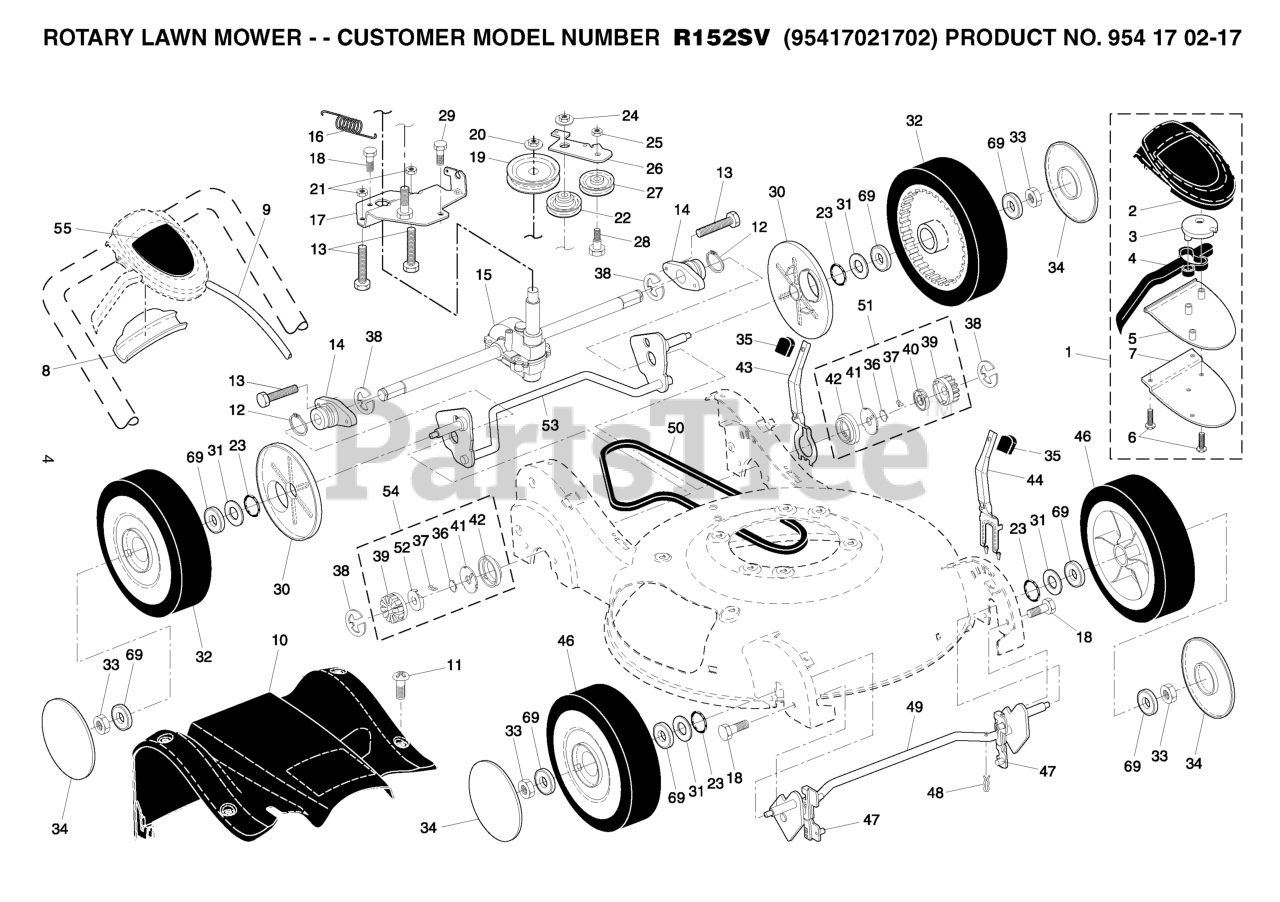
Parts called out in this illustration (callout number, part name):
1	CONTROL.DR.HV.RWGD.GRY/BLU
2	CASE.TOP.GRAY
3	PULLEY.CAM.DRIVE.CONTROL.HV
4	LEVER, DRIVE CONTROL
5	CASE BOTTOM
6	SCREW, PHILLIPS HEAD 10 X 5/8
7	BRACKET, DRIVE CONTROL
8	EZ WALK SNAP COVER PLATE
9	ASM.CABLE.
10	COVER ASM. DRIVE
11	SCREW
12	RETAINING RING (2 2)(3 2)
13	RP SCREW
14	BEARING.SUPPORT.ASSEM
15	TRANSMISSION.21.HI-VAC.EZ
16	SPRING.RETURN
17	BRACKET TRANSMISSION
19	RP PULLEY DRIVE
20	FLANGED LOCKNUT 3/8-16 ZINC
21	NUT
22	PULLEY.IDLER.V-BELT
23	O-RING
24	JAM NUT TI
25	NUT.CENTERLOCK.5/16-
26	ARM.IDLER.BZP
27	IDLER PULLEY
28	SHOULDER BOLT
29	SCREW 14-20 X 5/8
30	DUST COVER, WHEEL
31	WASHER.FLAT.1/2
32	WHEEL.9X2.25.PR.JUNG.BLK
33	HEX FLANGE LOCKNT
34	RB HUBCAP.3-SPOKE.SILVER
35	KNOB.SELECTOR.SPRG.H-GRY (2 2)
36	SPRING, TORSION
37	PAWL.DRIVE.21.EZ-WALK
38	E-RING 7/16 RE
39	GEAR, PINION
40	RETAINER.DRIVE.21.EZ-WALK.LT
41	DISC.DRIVE.21.EZ-WALK
42	SEAL.PINION
43	LEVER, SELECTOR, HEIGHT, REAR
44	LEVER, SELECTOR, HEIGHT, FRONT
46	WHEEL.9X2.25.LP.JUNG.BLACK
47	BUSHING.FRONT.TORQUE.SHAFT
48	SPRING RETAINER
49	SHAFT FRONT
50	BELT.DRIVE.EZ.WALK.HI-VAC
51	PINION ASSY, LH
52	RETAINER, DRIVE, RH
53	AXLE.ASM.REAR.TORQUE.BZP
54	PINION ASSY, RH
55	DECAL, DRIVE
69	BEARING.8".WHEEL
